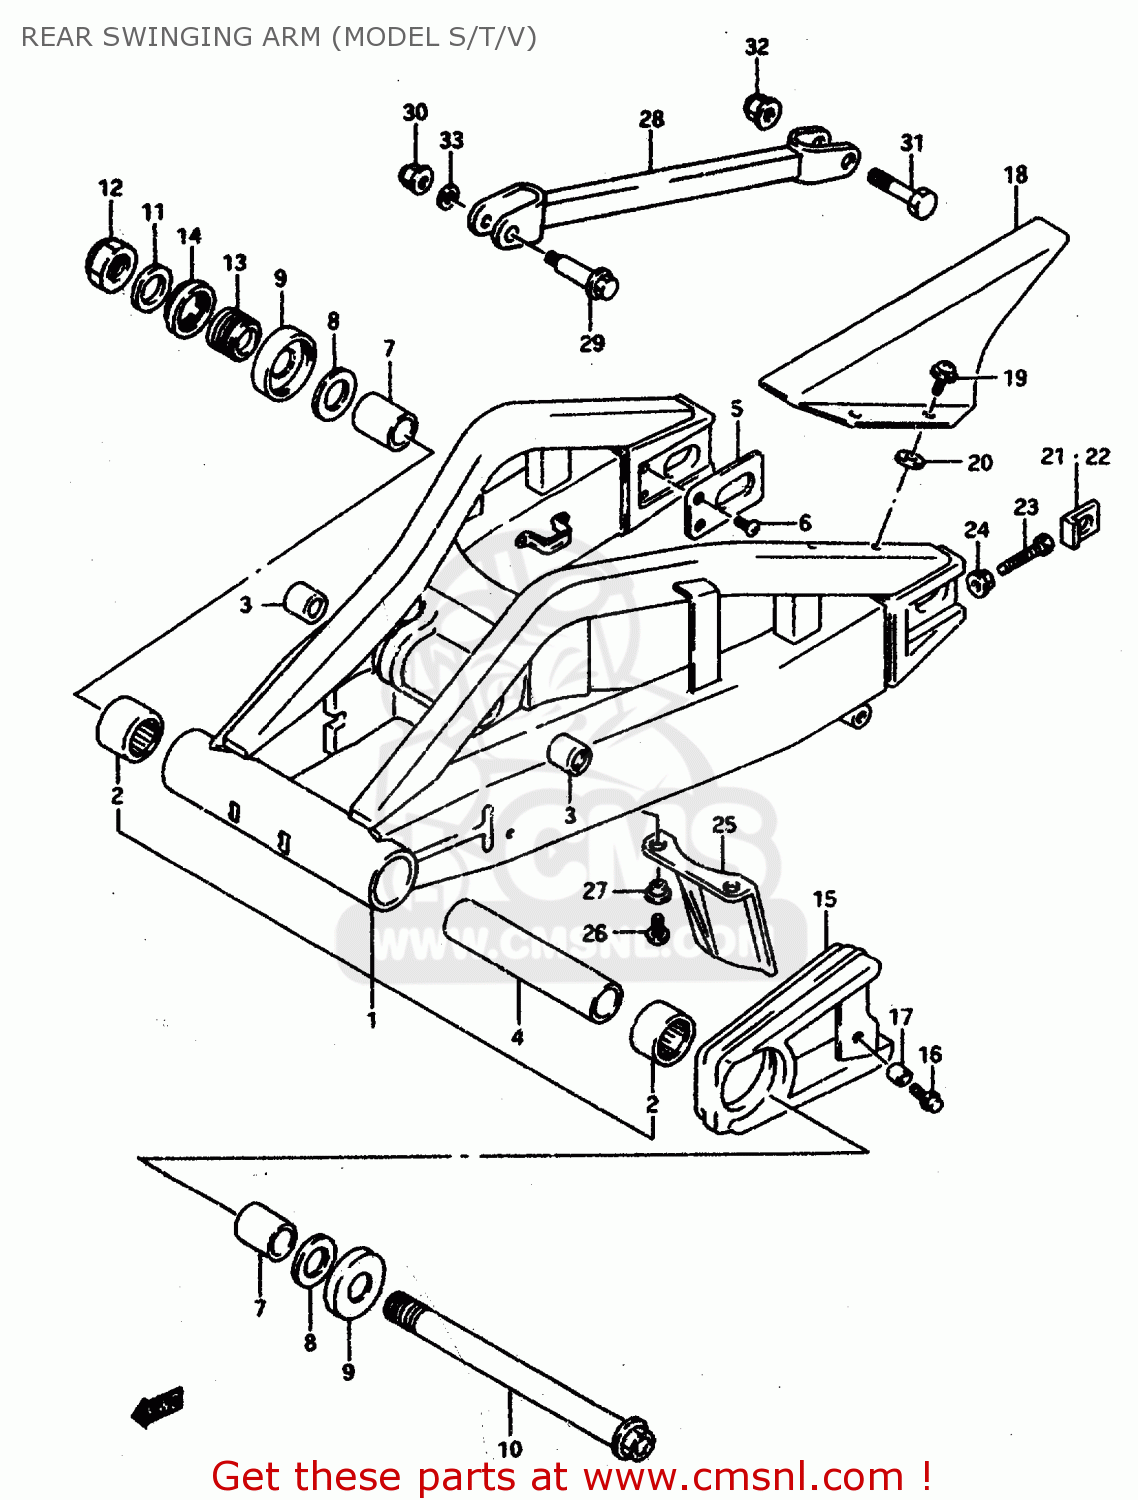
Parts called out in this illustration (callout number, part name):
1	SWING ARM ASSEMBLY,REAR
2	BEARING(30X40X25)
3	BEARING(17X24X20)
4	SPACER (25.4X31.8X157.9)
5	PLATE,RR SWING ARM BRKT
6	SCREW 6X10
7	SPACER,REAR SWING ARM PIVOT
8	WASHER
9	DUST SEAL,RR SWGARM PIVOT
10	SHAFT,REAR SWING ARM PIVOT
11	WASHER(25.2X42X3.2)
12	NUT
13	BOLT,REAR SWING ARM PIVOT
14	NUT,REAR SWING ARM PIVOT BOLT
15	BUFFER,CHAIN TOUCH DEFENSE
16	BOLT 6X20,WITH PLAIN WASHER
17	SPACER(6.5X10X7)
18	CASE,CHAIN
19	SCREW(6X20)
20	WASHER
21	WASHER,CHAIN ADJUSTER
22	WASHER,CHAIN ADJUSTER
23	BOLT(8X50)
24	NUT
25	GUARD,RR UNIT MUD
26	SCREW
27	WASHER
28	TORQUELINK,RR
29	BOLT
30	NUT
31	BOLT(10X37)
32	NUT
33	LOCK WASHER
